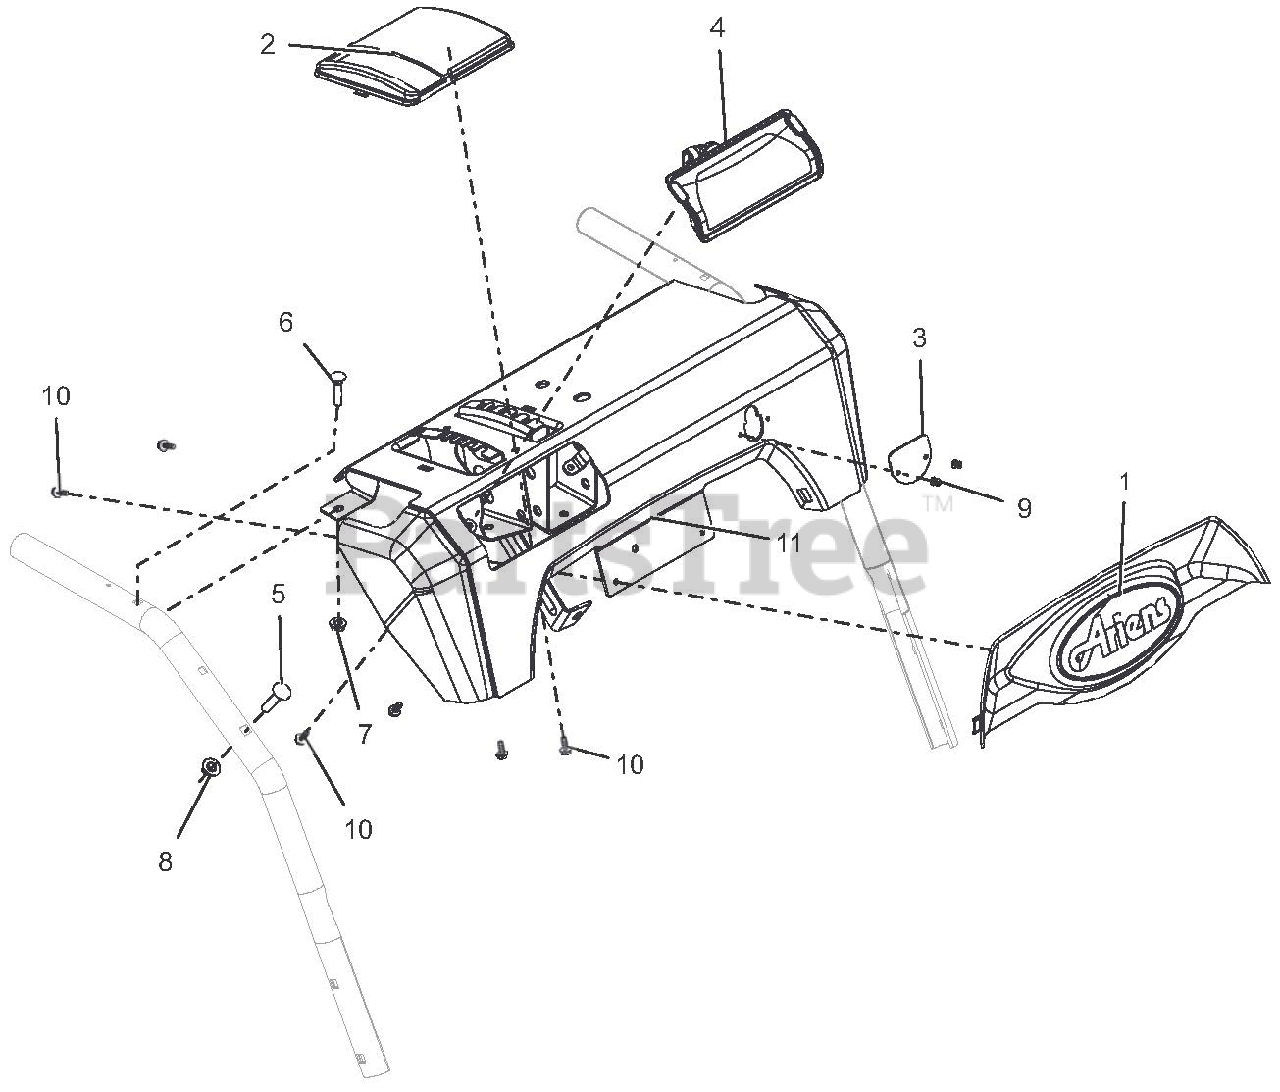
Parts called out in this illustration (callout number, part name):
1	DASH BEZEL, ARIENS LOGO - PRO
2	BEZEL, SHIFT ONLY
3	COVER, DASH BRKT, BRUSH
4	HEADLIGHT ASY, HOLO 15W 2 SHOT
5	@BLT-RDHDSQNK .31-18X1.50 G5YZ
6	BLT-RDHDXLSQNK.25-20X1.25 G5ZC
7	@NUT-LK-CTR-FLG .25-20 YWZC
8	@NUT-LK-TOP-FLG .31-18 YWZC
9	RVT-POP #43 .125X.313 STL ZINC
10	SCR-TAP #10X.50 BOSS INDHXHD
11	CONTROL PANEL W/DECAL
